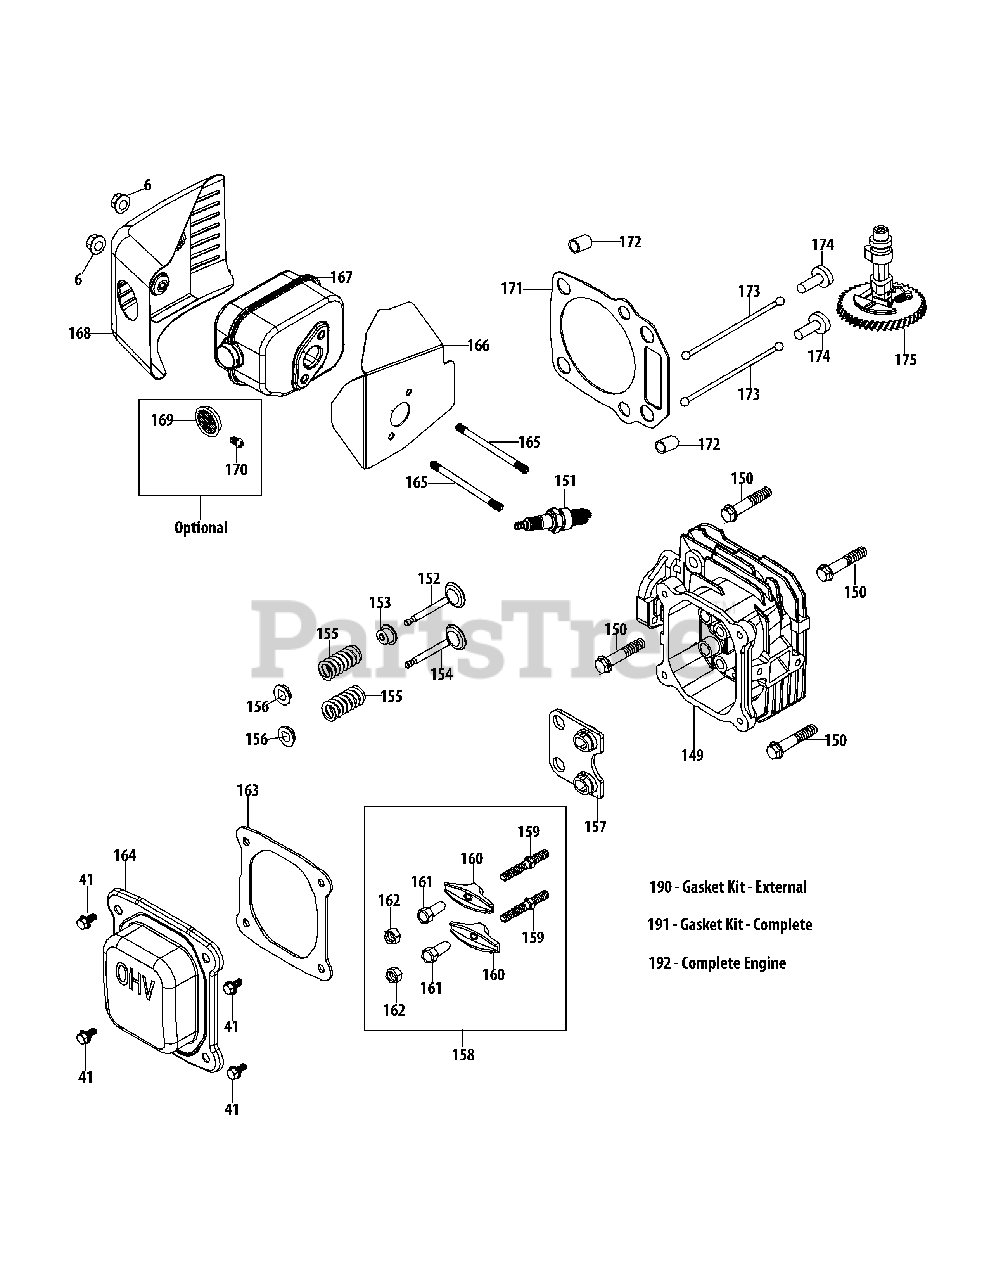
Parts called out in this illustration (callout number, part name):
6	Nut M6X10Mm
41	Bolt M6X14
149	Cylinder Head Assembly
150	Bolt M8X54
151	Spark Plug
153	Intake Valve Seal
155	Valve Spring
156	Valve Spring Retainer
157	Push Rod Guide
158	Rocker Arm Assembly
159	Rocker Arm Stud
160	Rocker Arm
161	Fulcrum Nut
163	Valve Cover Gasket
164	Valve Cover
165	Muffler Stud M6X95
165	Muffler Stud Assemlby
166	Muffler Gasket
167	Muffler Assembly
168	Muffler Shield
169	Spark Arrestor
170	Spark Arrestor Screw
171	Cylinder Head Gasket
172	Cylinder Head Dowel Pin 10×16
173	Push Rod Kit
175	Camshaft Assembly
190	Gasket Kit - External
191	Gasket Kit - Complete
192	Complete Engine
